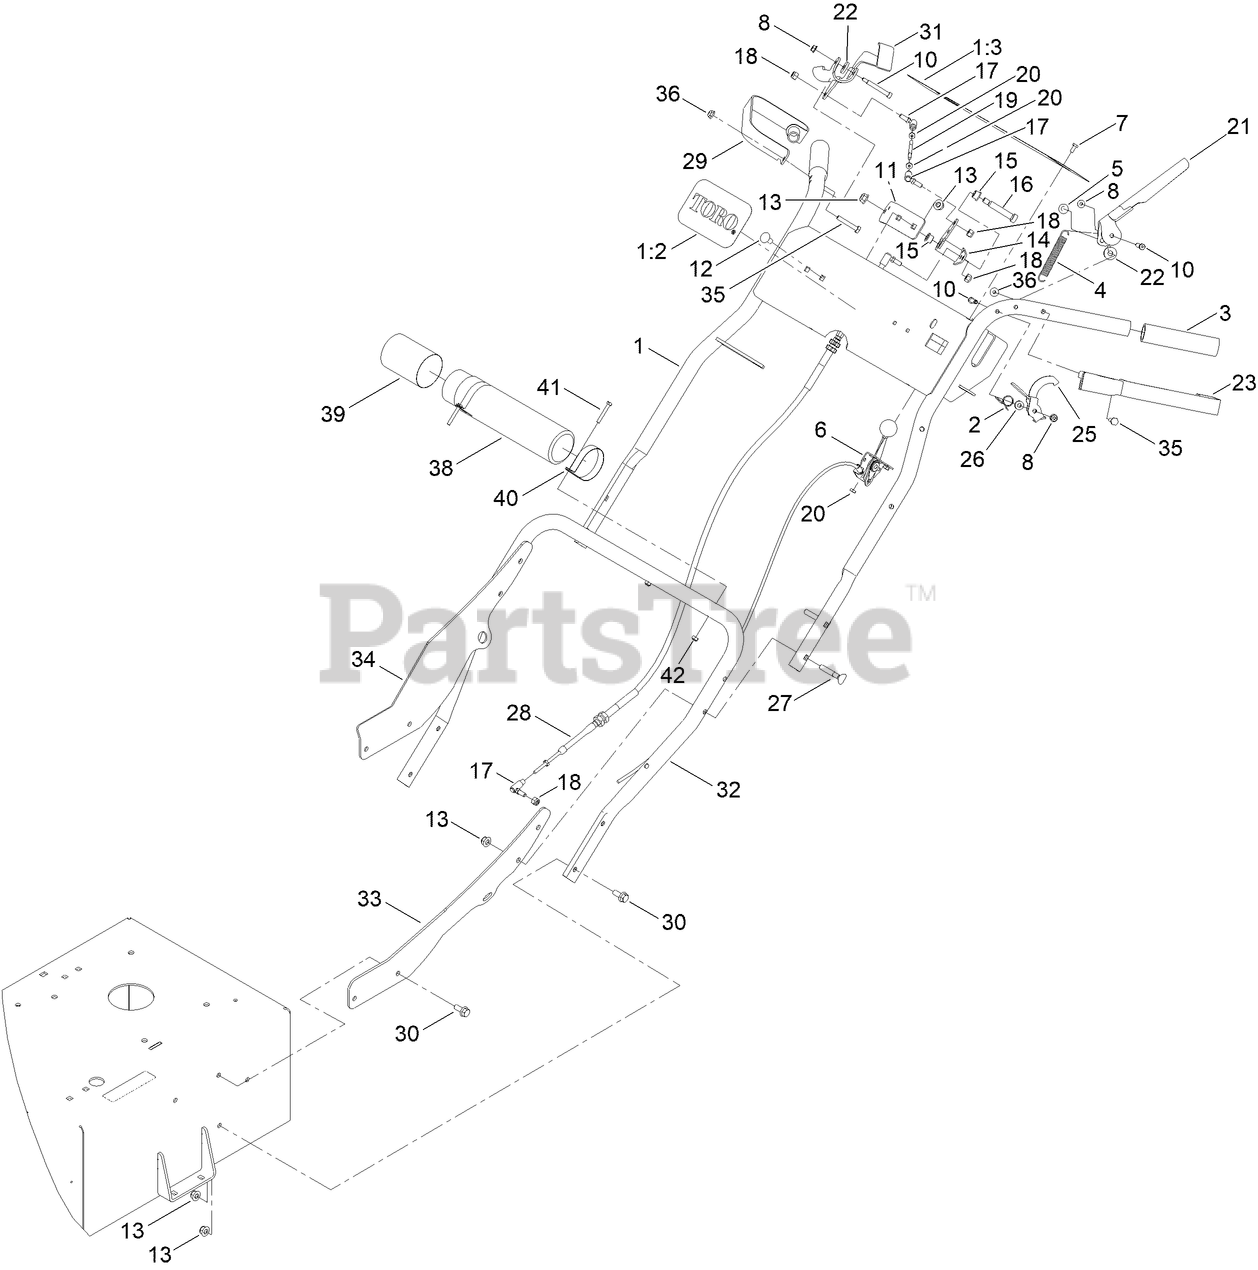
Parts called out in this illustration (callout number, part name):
1	HANDLE ASM
1:3	DECAL-OPERATION, SAFETY
2	SPRING
3	GRIP-FOAM
4	SPRING
5	NUT-PUSH
6	CABLE-THROTTLE
7	SCREW-HH
8	NUT-LOCK, FLANGE
10	BOLT-SHOULDER
11	MOUNT-BELL CRANK
12	BOLT-CARR
13	NUT-HF, NI
14	BELL CRANK ASM
15	BUSHING
16	SCREW-SHOULDER
17	BALL JOINT ASM
18	NUT-LOCK
19	LINK-CONTROL
20	NUT-HEX
21	HANDLE-CLUTCH
22	WASHER-FLAT
23	GUARD-KNUCKLE
25	LOCKOUT
26	SPACER
27	SCREW-HANDLE
28	CABLE-TRACTION
29	GUARD- KNUCKLE
30	SCREW-HHF
31	HANDLE-TRACTION
32	HANDLE-LOWER
33	BRACE-HANDLE [BLACK]
34	BRACE-HANDLE [BLACK]
35	SCREW-HH
36	NUT-HF
38	TUBE-MANUAL
39	CAP-HOUSING
40	CLAMP-R
41	SCREW-SHH
42	NUT-LOCK, NI
